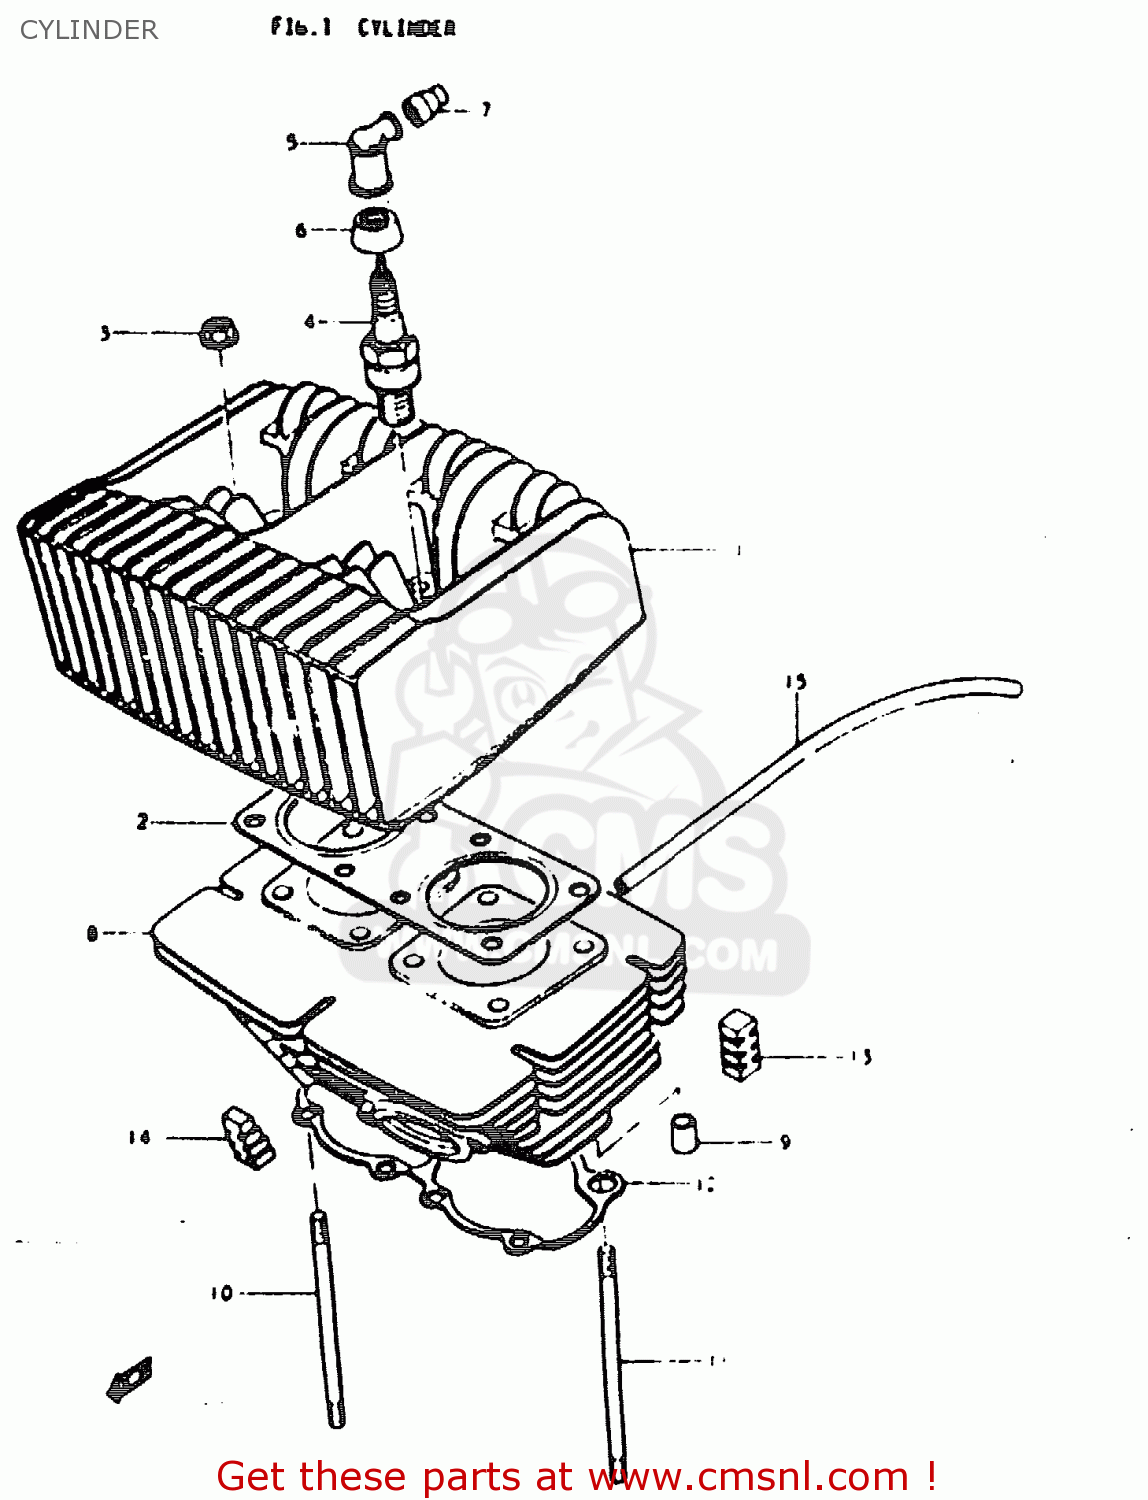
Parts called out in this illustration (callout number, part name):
1	CYLINER HEAD
2	GASKET, CYLINDER HEAD
3	NUT
4	PLUG,SPARK
5	CAP, SPARK PLUG
6	SEAL,SPARK PLUG
7	SEAL, CORD
8	CYLINDER
9	PIN
10	STUD
11	STUD
12	GASKET, CYLINDER (MCA)
13	PAD,CYLINDER
14	RUBBER PAD, CYLINDER FRONT
15	HOSE
